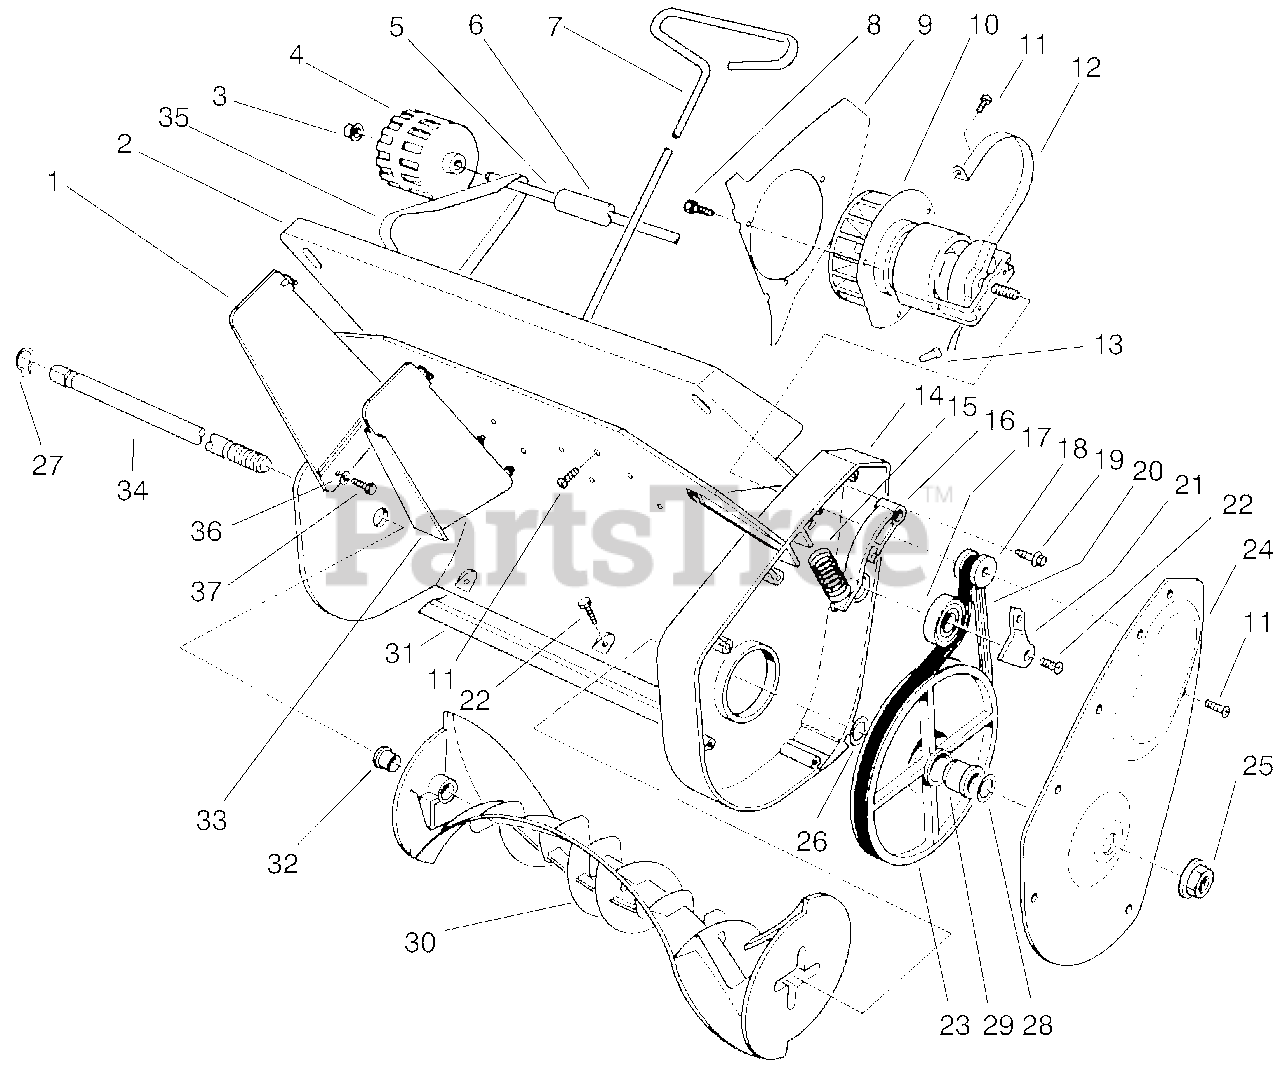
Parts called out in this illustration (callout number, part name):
1	Vane-Outer
2	Mount-Vane
3	Nut-Push On
5	Shaft-Axle
6	Sleeve-Axle
7	Rod-Vane Adjustment
8	Screw-Self Tapping
9	Baffle-Air
11	Screw-Self Tap. Pan Hd.
12	Mount-Motor
13	Connector-Wire
15	Spring-Compression Idler
16	Arm-Idler
17	Bearing-Ball
18	Pulley-Drive
19	Screw-Hex. Washer Hd.
20	Belt-Drive
21	Retainer-Idler Pulley
22	Screw-Self Tap. Pan Hd.
23	Pulley-Driven
24	Cover-Belt Case
25	Nut-Flange Lock
26	Washer-Thrust
27	Ring-Retaining
28	Washer-Thrust
29	Bushing-Rotor
32	Bushing-Rotor
33	Vane-Center
34	Shaft-Rotor
35	Bracket-Wheel R.H.
37	Screw-Self Tapping
